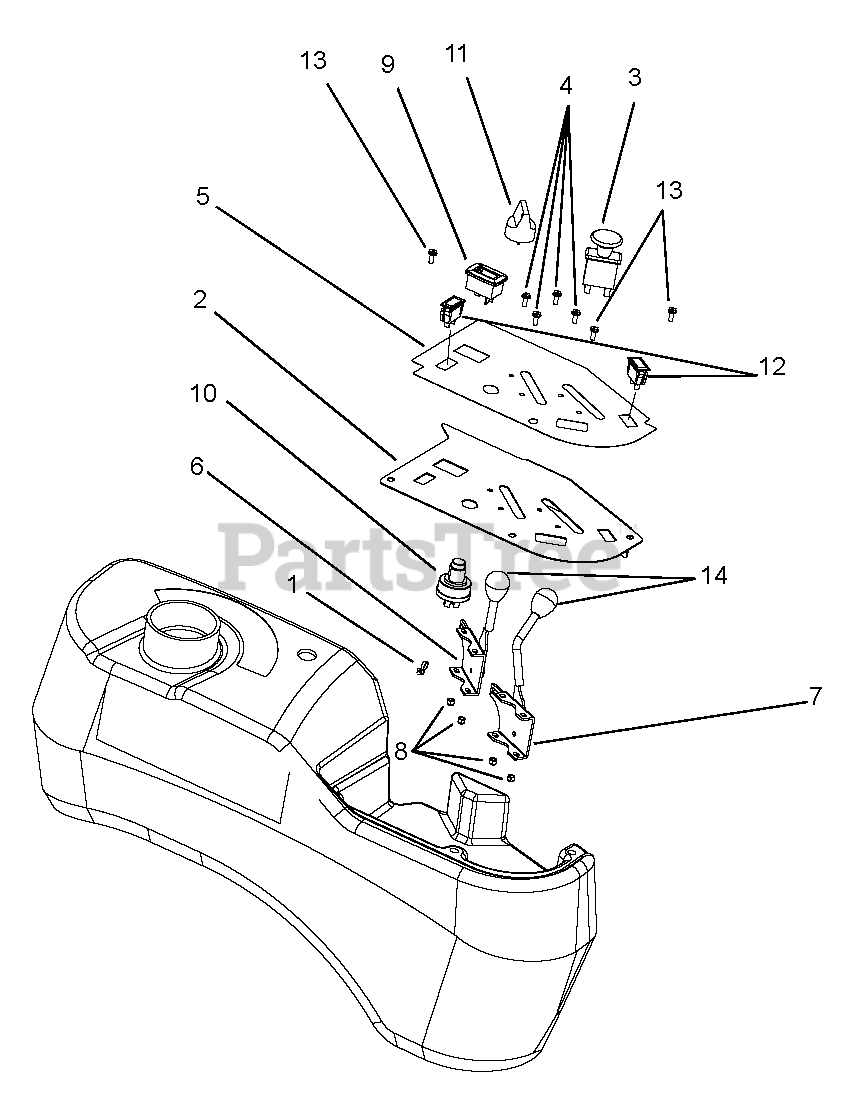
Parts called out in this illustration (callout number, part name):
1	Cable Tie w/ Tree (.25 HOLE)
2	Panel, Control
3	Switch, Clutch
4	Screw, Machine 10-24 x .50 Hex Washer Head
5	Decal, Control Panel (992200, 201, 203,197, 198)
6	Cable, Pro-Control Choke
7	Cable, Pro-Control Throttle
8	Nut, Locking Nyloc 10-24 w/Insert YWZC
9	Meter, Hour with Maintenance
10	Switch, Ignition
11	Key, with Shield
12	Light, Indicator
13	Screw, Machine 10-24 x .50 Hex Washer Head Stainless
14	Knob, Control, Black .38-16 x .50
